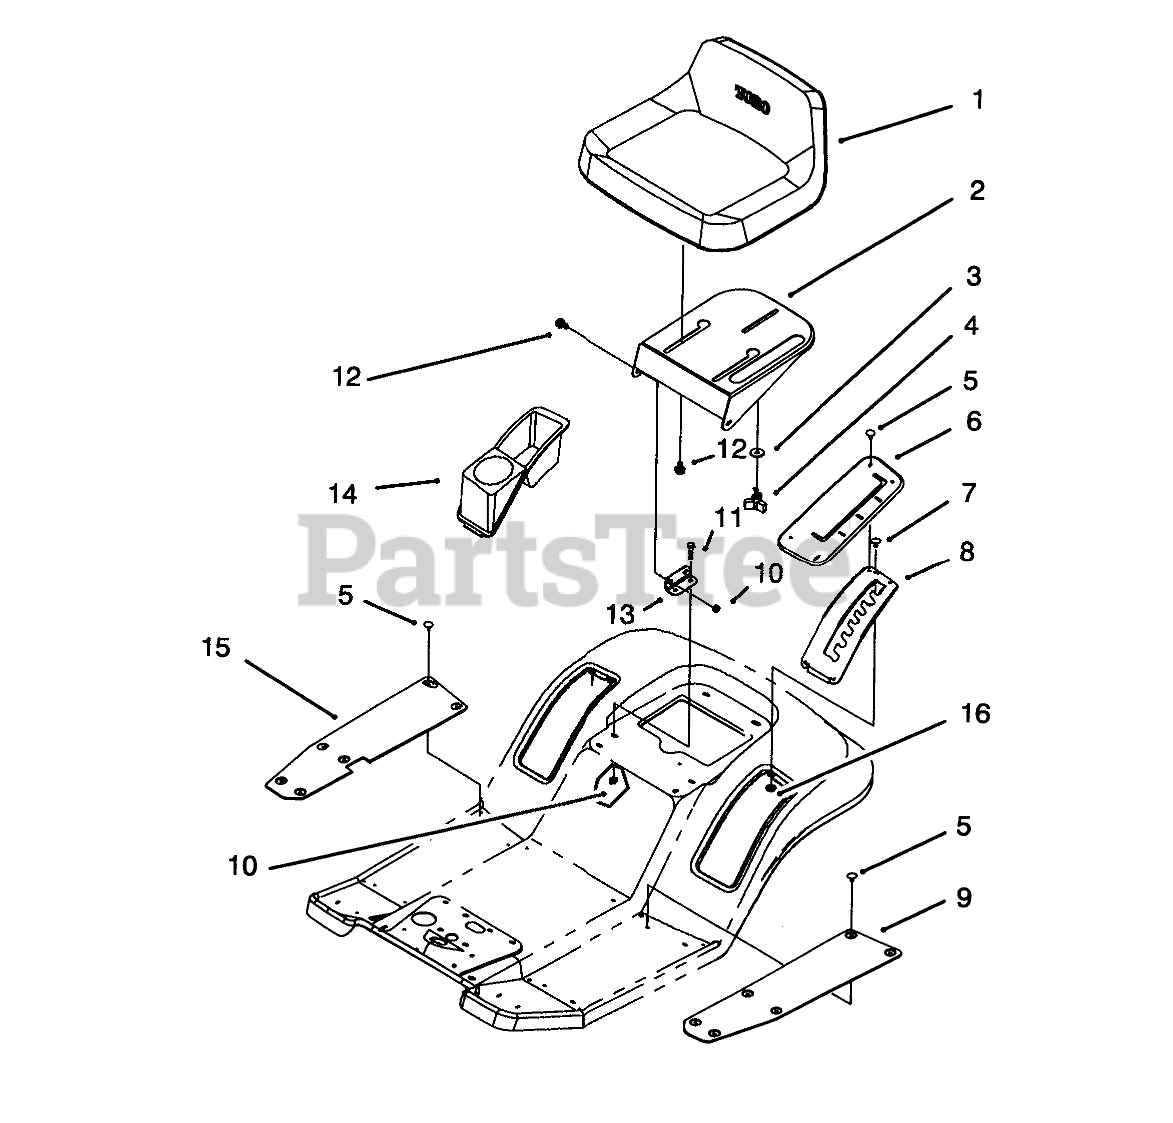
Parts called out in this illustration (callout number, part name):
1	SEAT
2	Support-Seat
3	WASHER-PIVOT
5	FASTENER-PANEL
6	COVER-HOC
7	RIVET-POP
8	Gate-H.O.C.
9	MAT-FOOT, LH
10	NUT-LOCK, NI
11	SCREW-HH
12	BOLT-SHOULDER
13	Bracket-Seat Hinge
14	TRAY-FENDER
15	MAT-FOOT, RH
16	WASHER-FLAT
